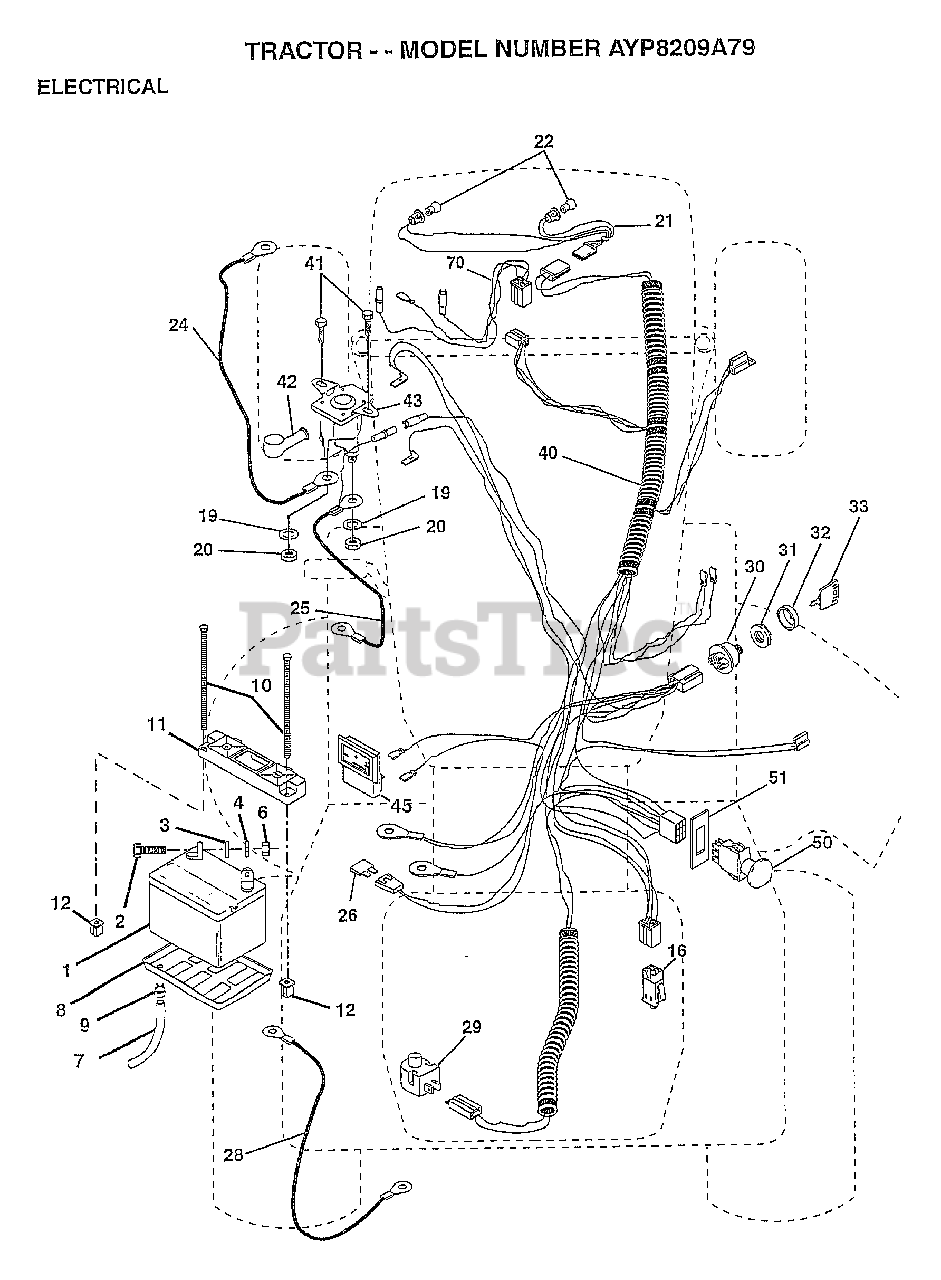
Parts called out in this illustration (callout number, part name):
2	BOLT LT
3	WASHER
4	LOCKWASHER
7	"DRAIN TU T, BATT"
8	"TRAY T, BATTERY"
9	HOSE CLAMP T
11	HOLDDOWN BATTERY
16	SWITCH INTERLOCK
20	NUT
21	"HARNESS,LIGHT SOC"
24	CABLE-BATTERY T
25	CABLE.6GA.12.5.
26	FUSE HYT
28	CABLE T
29	SWITCH SEAT
30	SWITCH IGN 4POS
31	NUT IGNITION
32	COVER KEY SWITCH
33	KEY
40	"HARNESS,IGNITION"
41	SCREW
45	AMMETER
50	PTO SWITCH.BLK
51	RING RETAIN PTO
70	HARNESS.ENG.VANII
